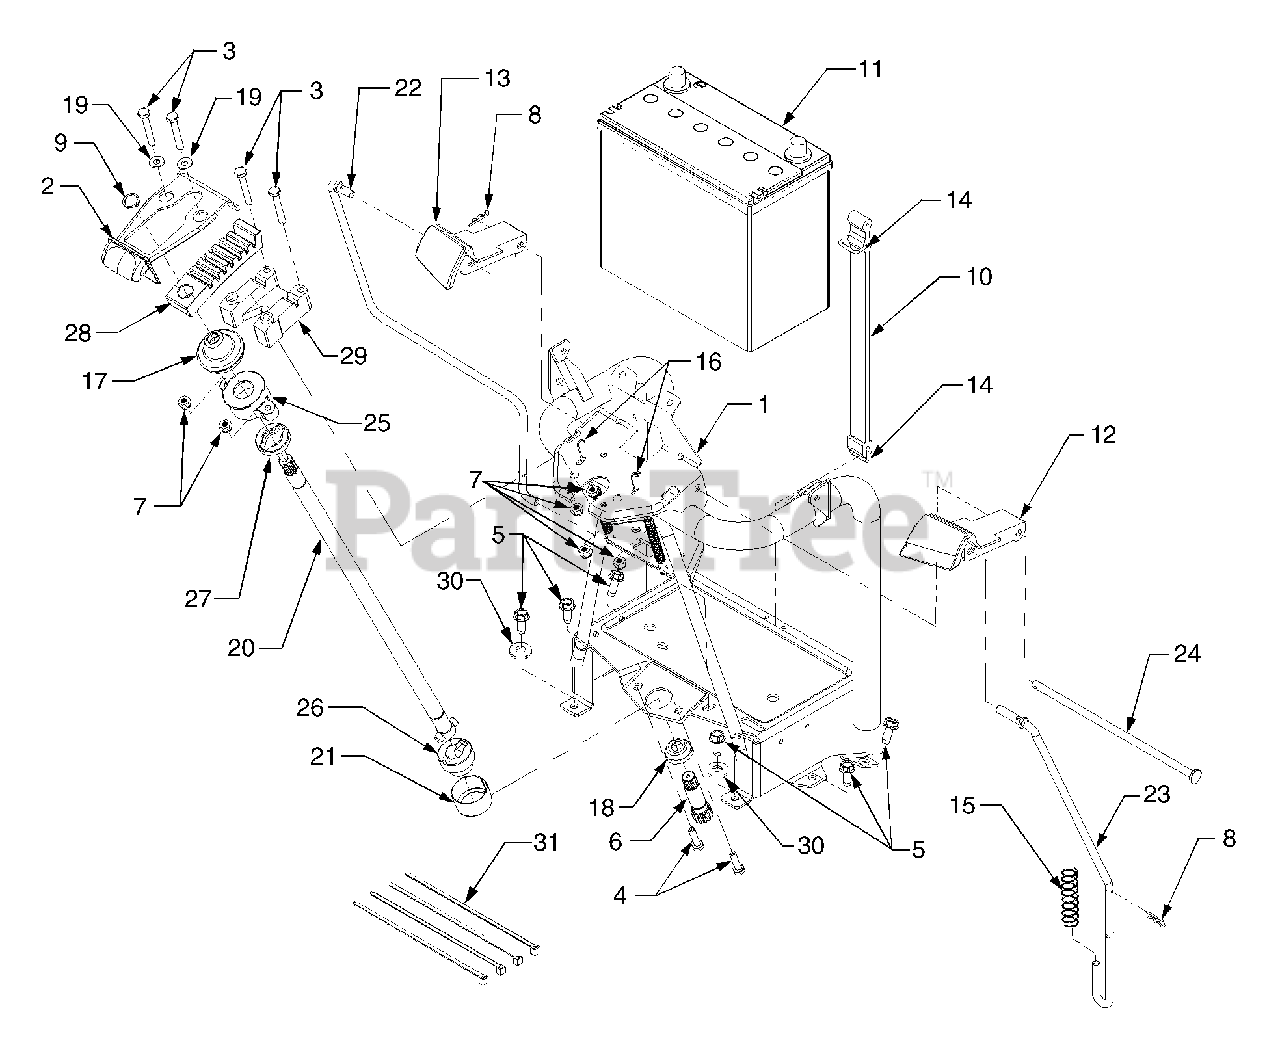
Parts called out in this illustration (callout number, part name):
1	Pedestal Assembly
2	Handle, Tilt
3	Screw, Hex Cap 1/4-20 x 1.75 GR5
4	Screw, Hex Cap 1/4-20 x 1.0 GR5
5	Screw, Hex Wash. Hd. Tapp 5/16-18 x .75
6	Shaft, Lower Steering
7	Nut, Hex Insert Lock, 1/4-20
8	Pin, Internal Cotter
9	Ring, Retaining, .56 Dia Shaft
10	Strap, Battery
11	Battery
12	Lever, Park Brake
13	Lever, Cruise
14	Hook, Wire Rectangular
15	Spring, Compression, .676 x 2.57
16	Spring, Extension
17	Boot, Tilt Wheel Coupling
18	Boot, Shaft Cover
19	Washer, Flat, .271 x .63 x .065
20	Shaft, Upper Steering
21	Bearing, Sleeve, 1.44 x 1.5 x .812
22	Rod, Cruise Control
23	Rod, Parking Brake
24	Rod, Cruise/Brake Pivot
25	Housing, Tilt Wheel Coupling
26	Coupling Half, Bottom
27	Coupling Half, Top
28	Index, Tilt Steering
29	Block, Tilt Steering
30	Washer, Flat, .344 x .688 x .065
31	Cable Tie, Harness
